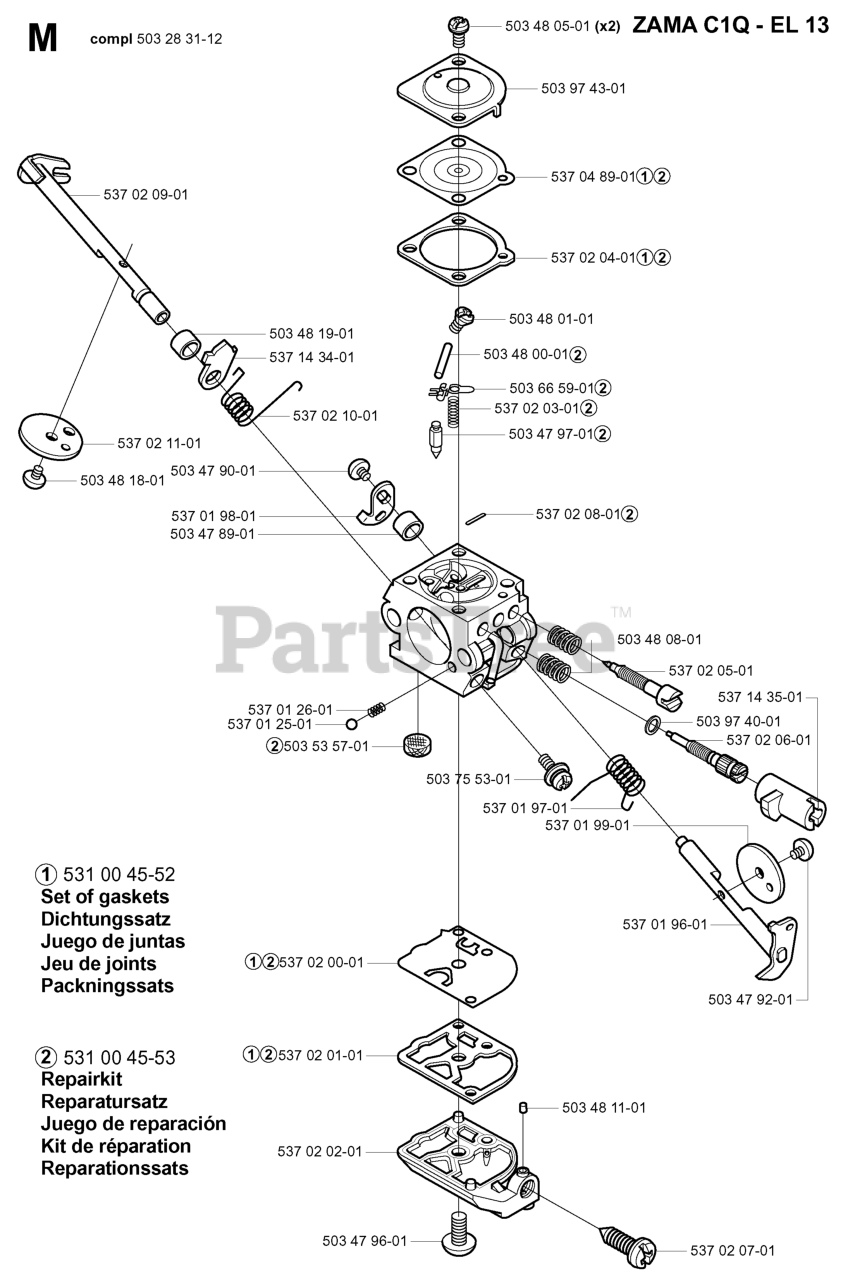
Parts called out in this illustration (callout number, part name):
1	Kit, Sealed CVT Cover
2	SCREW, 1/4-15 X .50 HI-LO HEX
3	SCREW, M6 X 16 TT HX FL HD
4	CLAMP, HOSE, CTB 64MM
5	COVER, CVT OUTER
6	HOSE, INLET, COVER, CVT
7	BRACKET, INLET, COVER, CVT
8	GASKET, COVER, CVT
9	CAP, INLET COVER, CVT
10	FILTER, INLET, COVER, CVT
11	HOSE, OUTLET, CVT
